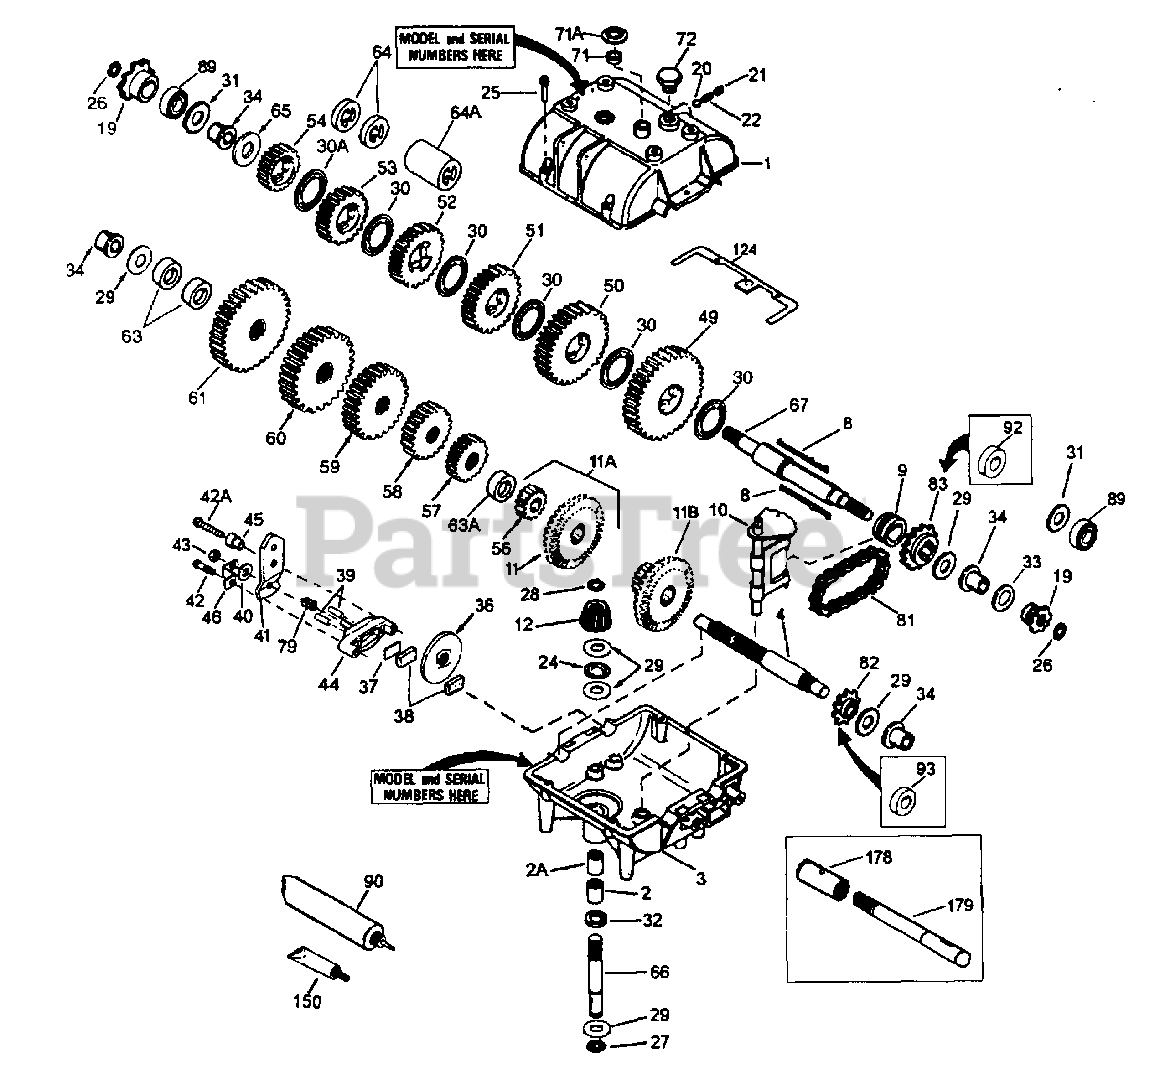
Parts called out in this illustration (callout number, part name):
1	Case, Transmisson
2	Needle Bearing Grease Spec
2A	Needle Bearing
3	Case, Transmission
8	Shift Key
9	Shift Collar
10	Shift Rod & Fork
11	Bevel Gear
12	Bevel Pinion
20	Steel Ball, 5/16" dia.
21	Set Screw, 3/8-16 x 3/8"
22	Spring
24	Thrust Bearing
25	Screw, 1/4-20 x 1-1/4" (6)
27	Retaining Ring
28	Retaining Ring
29	Washer (6)
30	Washer (5)
32	O Ring
34	Flanged Bushing
49	Spur Gear
50	Spur Rear
51	Spur Gear
52	Spur Gear
53	Spur Gear
56	Spur Gear
57	Spur Gear
58	Spur Gear
59	Spur Gear
60	Spur Gear
65	Washer
66	Input Shaft
67	Shifter & Brake Shaft
71	Square Cut Ring
72	Threaded Plug
81	Roller Chain
82	Sprocket
83	Sprocket
90	Grease
150	Gasket Eliminator
178	Coupling
179	Connector Shaft
